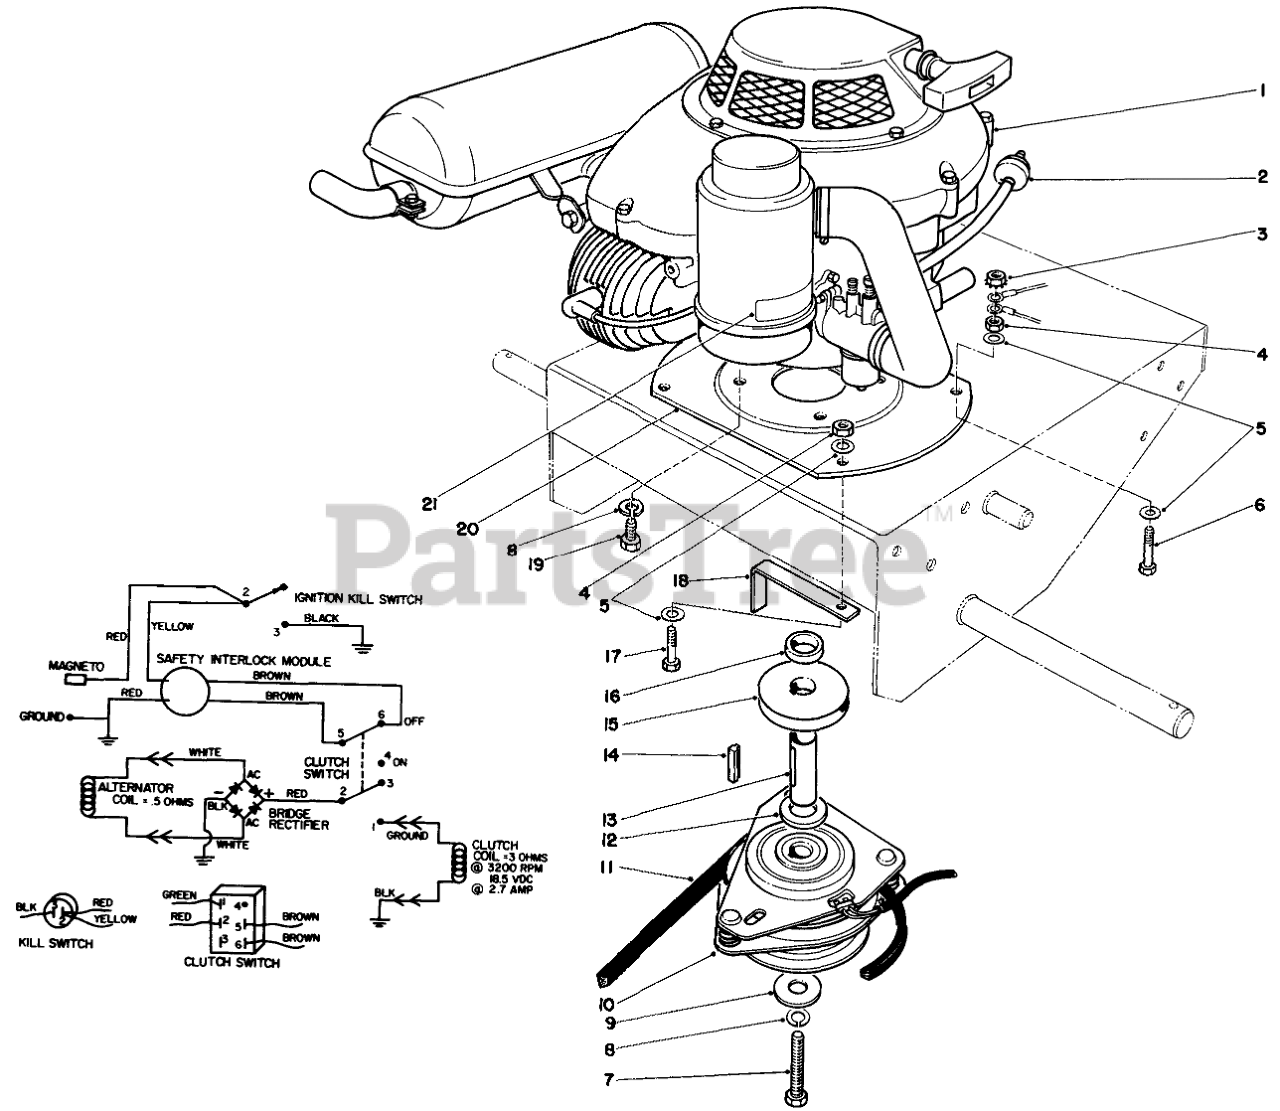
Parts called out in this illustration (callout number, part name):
1	Engine Assembly
2	Nut
3	NUT-KEPS
4	NUT-LOCK, CONE
5	WASHER-PLAIN
6	SCREW-HH
7	CAPSCREW
8	WASHER-LOCK
9	WASHER-CLUTCH
10	CLUTCH/BRAKE
11	V-BELT, DRIVE
12	SPACER-LOWER
13	Adapter-Crankshaft
14	CRANKSHAFT KEY
15	Pulley-Drive
16	UPPER SPACER
17	SCREW-HH
18	Retainer-Clutch
19	CAPSCREW
20	ENGINE PLATE
21	DECAL
